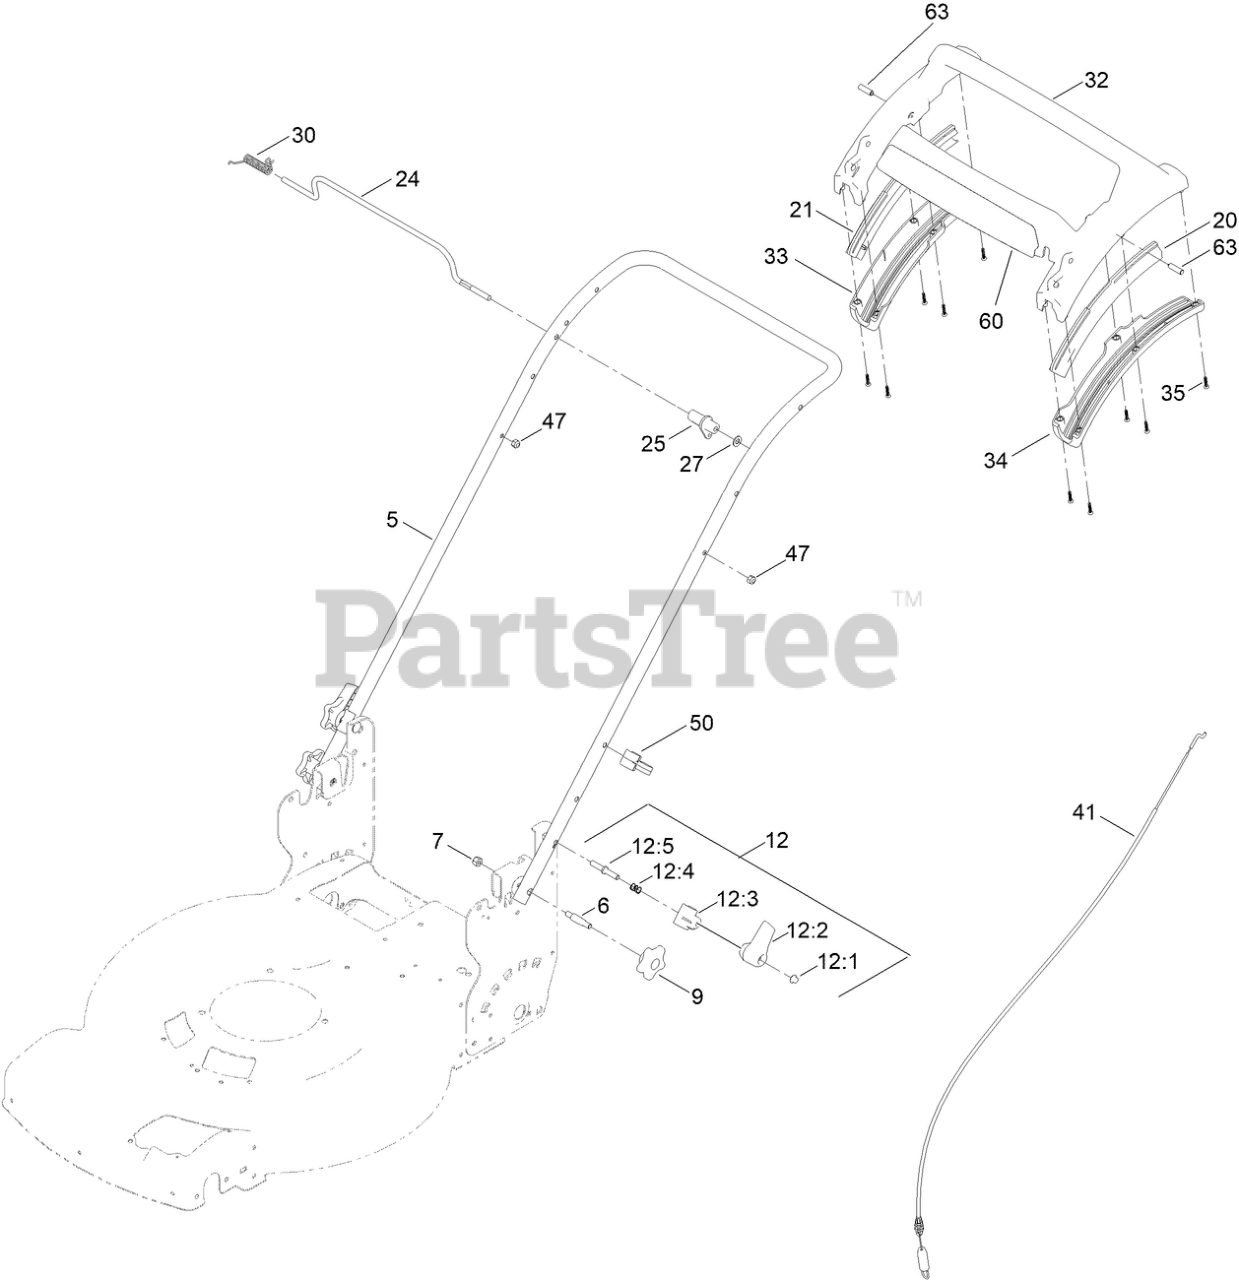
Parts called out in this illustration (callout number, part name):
5	HANDLE-CURVED
6	BOLT-SHOULDER, HANDLE
7	NUT-LOCK, NI
9	KNOB-HANDLE
12	QUICK RELEASE ASM
12:1	NUT-PUSH
12:2	LEVER-RELEASE
12:3	ANCHOR-SPRING
12:4	SPRING-COMPRESSION
12:5	ROD-RELEASE
20	GUIDE-CURVED, LH (RWD)
21	GUIDE-CURVED, RH (RWD)
24	ROD-CONTROL, TRACTION
25	LEVER-TRACTION, RWD
27	WASHER-PLAIN
30	SPRING-TORSION
32	HANDLE-PERSONAL PACE, CURVED
33	BOTTOM-HANDLE, RH
34	BOTTOM-HANDLE, LH
35	SCREW-PPH
41	CABLE-TRACTION, RWD (PP)
47	NUT-LOCK, NI
50	GUIDE-CABLE
63	PIN-HANDLE, PP
